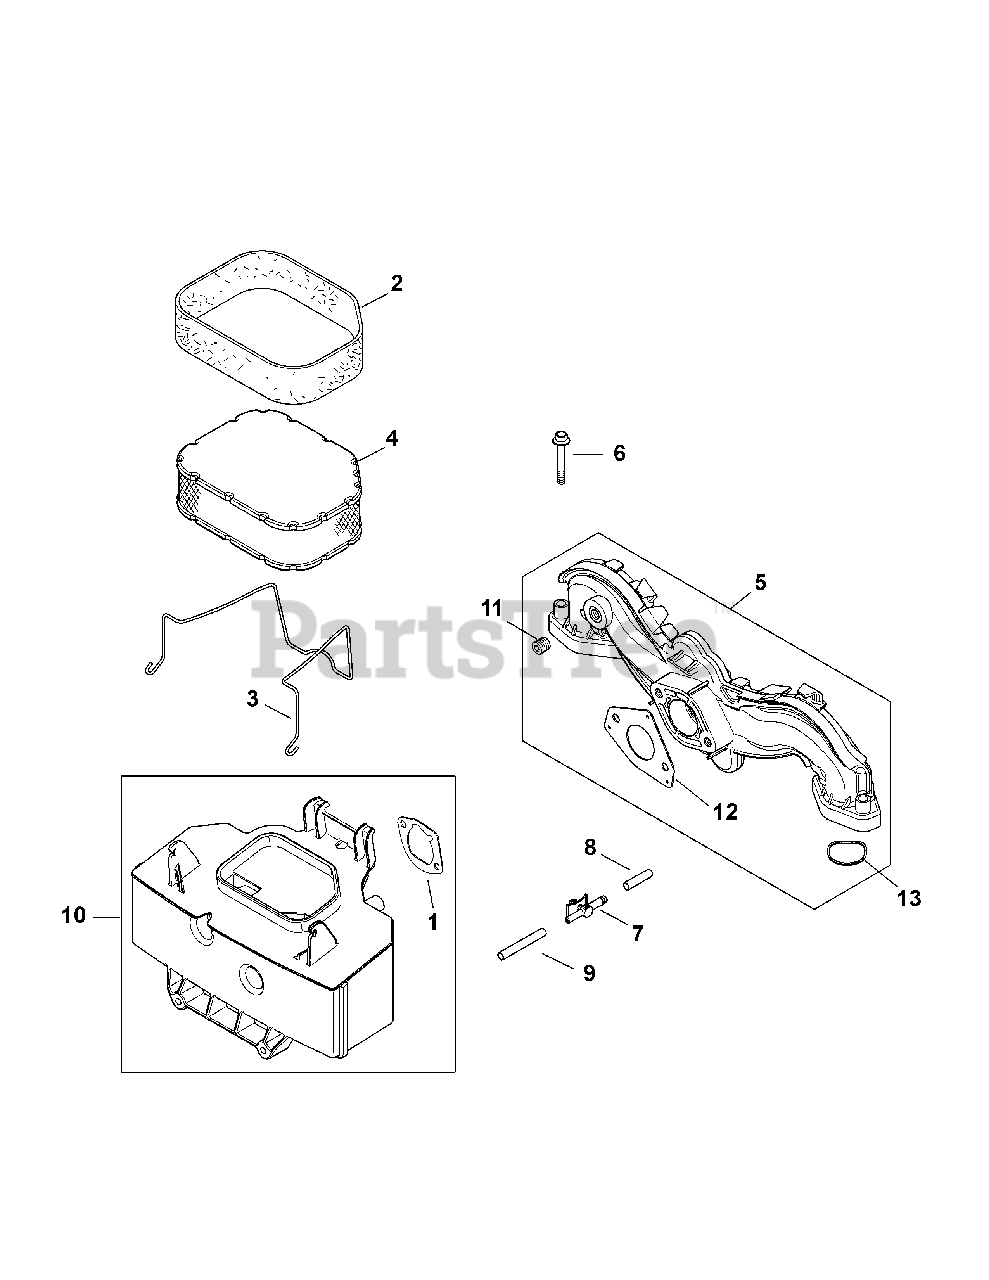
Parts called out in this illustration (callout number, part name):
1	Air Cleaner Base Gasket
2	Pre-Cleaner Element
3	Air Cleaner Element Latch
4	Air Filter & Pre-Cleaner Elements
5	Intake Manifold Kit
6	Flange Screw, M6 x 1.0 x 40
7	Evaporative Connector
8	Evaporative Mask
9	Evaporative Hose, 20"
10	Air Cleaner Base
11	Pipe Plug, 1/8
12	Carburetor Gasket
13	Intake Port O-Ring
